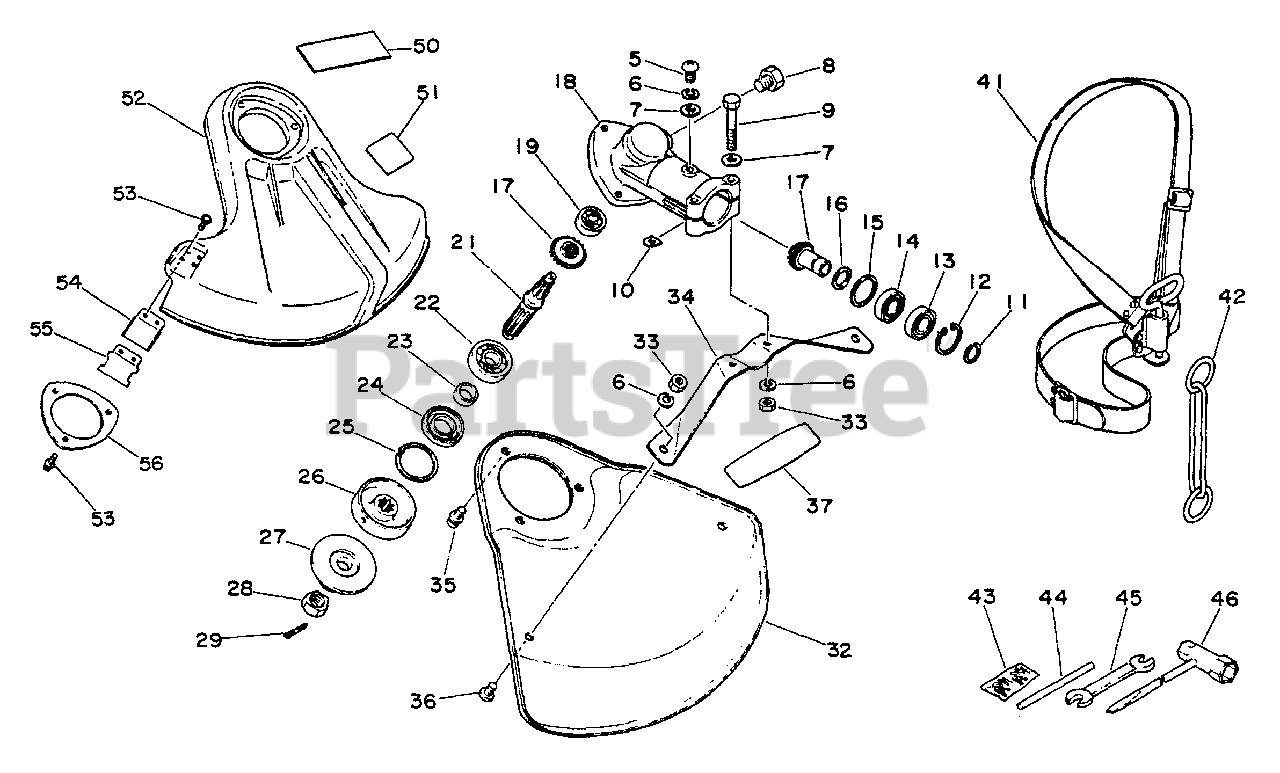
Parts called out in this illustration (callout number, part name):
5	SCREW 5×10
6	WASHER, SPRING 5
7	WASHER, FLAT 5.5×10×0.8
8	BOLT 8×8 SP
9	BOLT 5×35 SP
11	RING, RETAINING
12	RING, SNAP Ø22
13	BEARING, BALL 6900Z
14	BEARING, BALL 6900
18	CASE, GEAR
19	BEARING, BALL 626
21	SHAFT, GEAR
22	BEARING, BALL 6000
24	SEAL, OIL
25	RING, SNAP Ø25
26	PLATE, ADAPTER - UPPER
27	PLATE, ADAPTER - LOWER
29	PIN, COTTER 2×22
32	SHIELD
33	NUT M5
34	BRACKET, SHIELD
35	SCREW 5×10
36	SCREW 5×8
37	LABEL - ECHO
41	SHOULDER STRAP ASSY
42	HOOK
43	PIN, COTTER 2×22 (PKG. OF 10)
44	TOOL, LOCKING 5×120 MM
45	SPANNER 8×10
46	T-WRENCH 17x-19 L200
50	LABEL, ECHO
52	SHIELD ASSY
53	KNIFE, TRIMMER LINE
54	PROTECTOR
55	SCREW 5×16
56	PLATE, SHIELD Ø49.5 MM
